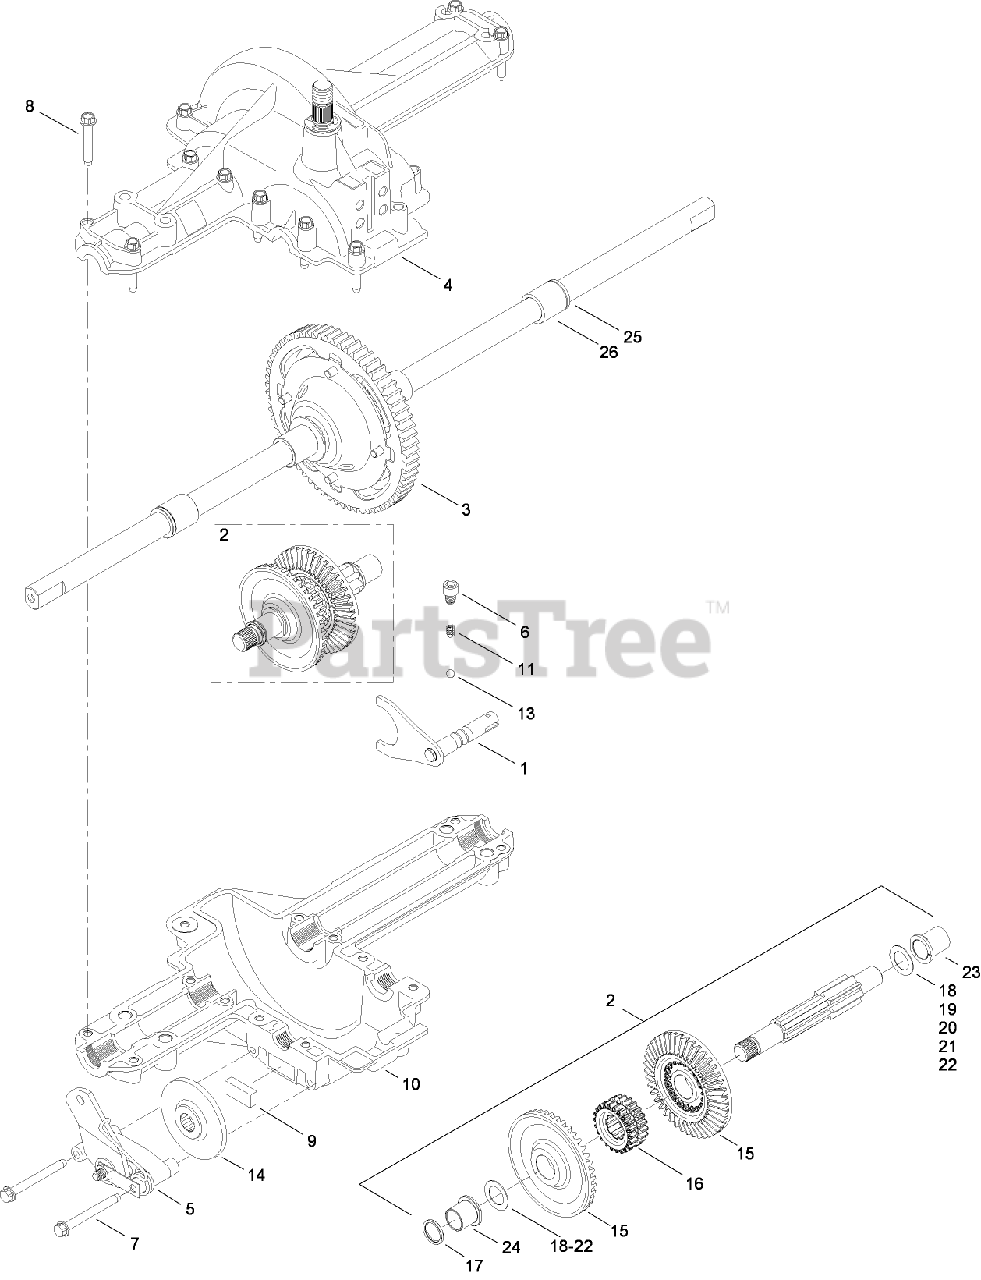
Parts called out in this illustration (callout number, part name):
1	SHIFT FORK ASM
2	DRIVE SHAFT ASM
3	DIFFERENTIAL ASM
4	UPPER HOUSING ASM
5	BRAKE ASM
6	SCREW-TAP
7	SCREW-HWH
8	SCREW-TAP
9	PUCK-BRAKE
10	HOUSING-LOWER
11	SPRING-DETENT
13	BALL-DETENT
14	DISC-BRAKE
15	GEAR-BEVEL, 42T (SPLINE)
16	COLLAR-CLUSTER
18	WASHER-FLAT
19	WASHER-FLAT
20	WASHER-FLAT
21	WASHER-THRUST
22	WASHER-THRUST
23	BEARING-FLANGE
24	BEARING-FLANGE
26	BEARING-SLEEVE
